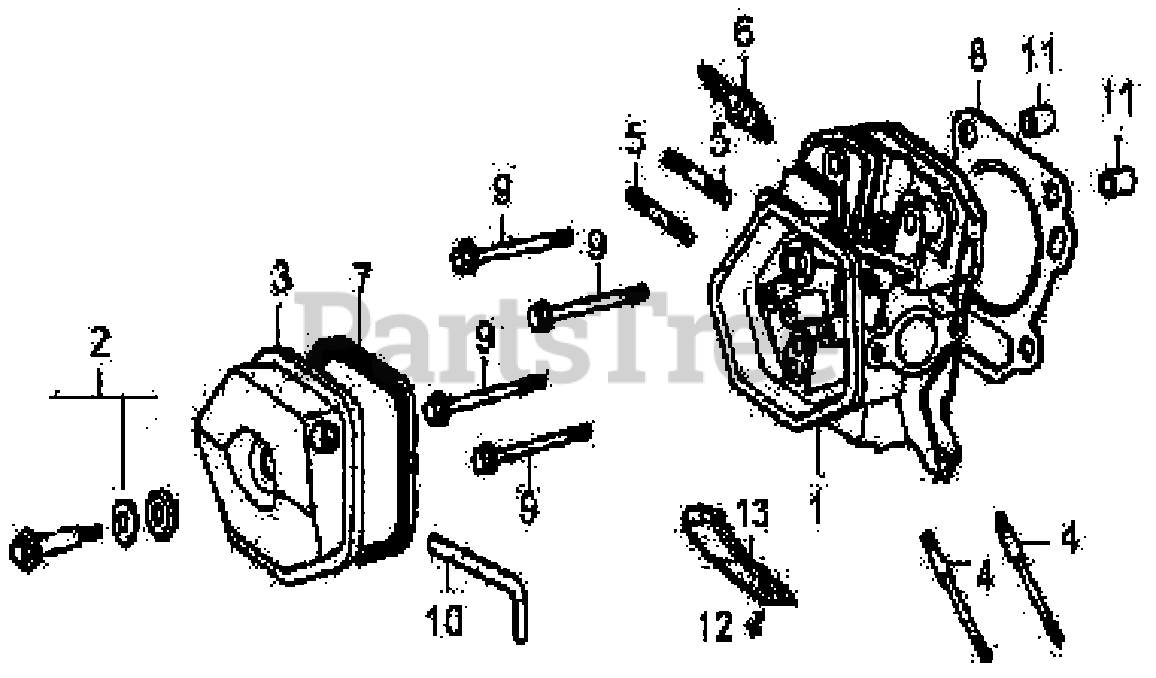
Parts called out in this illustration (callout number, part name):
1	HEAD COMP., CYLINDER
2	BOLT COMP., HEAD COVER
3	COVER COMP. HEAD
4	BOLT, STUD, INTAKE6-8×106
5	BOLT, STUD, EXHAUST 8×34
6	SPARK PLUG
7	GASKET, CYLINDER
8	SEALING PAD, CYLINDER
9	BOLT, FLANGE M10×80
10	TUBE, BREATHER
11	PIN, DOWEL 12×20
12	BOLT, FLANGE M6×12
